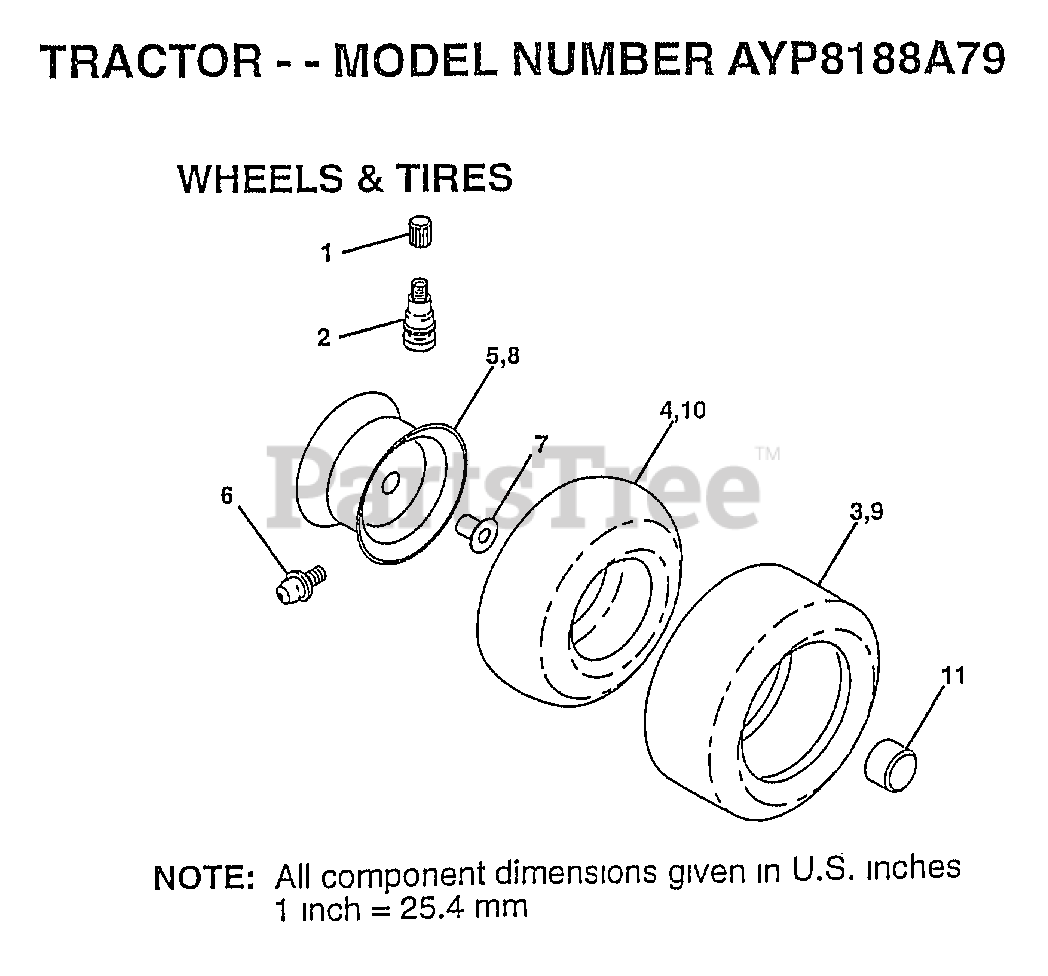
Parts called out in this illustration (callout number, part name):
1	VALVE CAP
2	VALVE STEM LT
4	TUBE.16X6.5/7.5-8
5	"RIM ASM 8"" FRT"
6	ZERK FITTING M
7	"FLANGE, BEARING"
8	"RIM ASM 12"" REAR"
10	TUBE.23X8/10-12
11	HUB CAP
